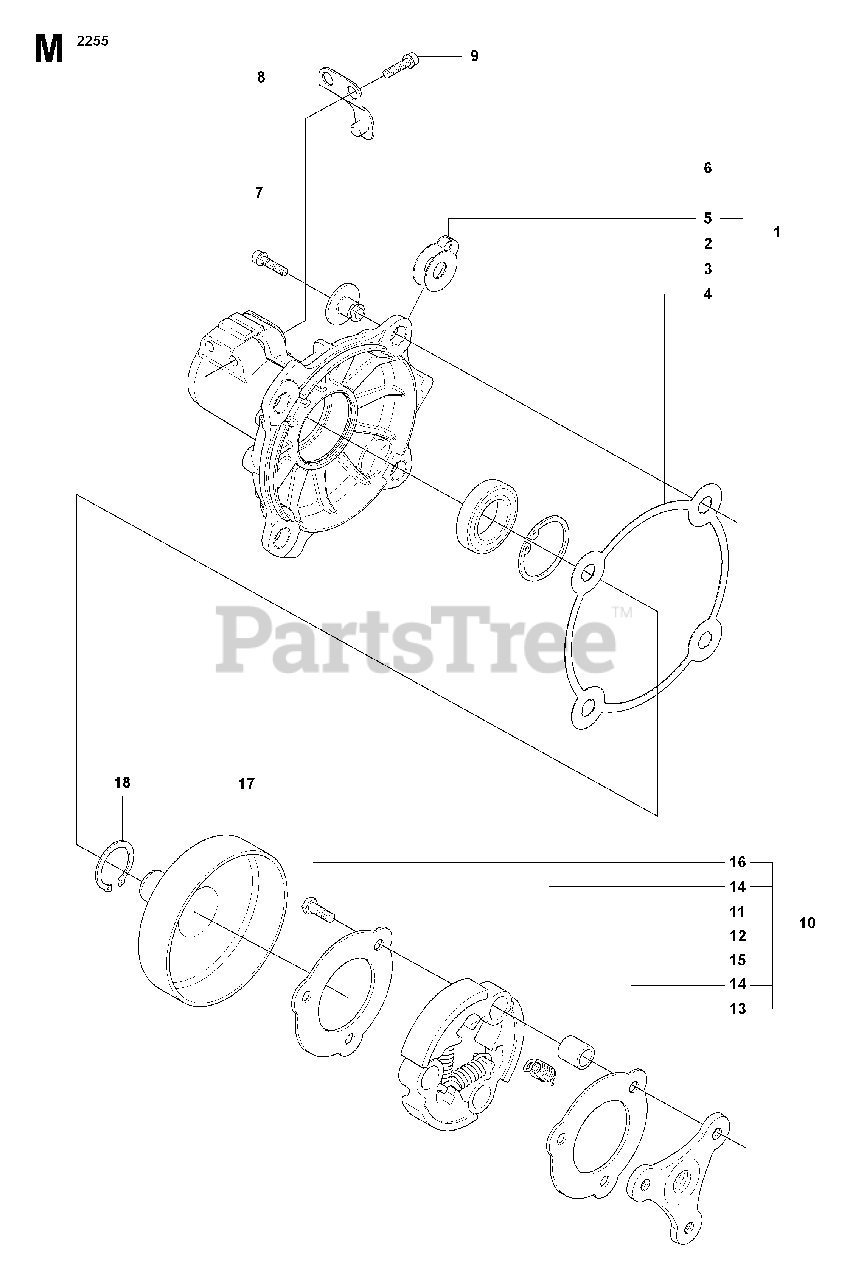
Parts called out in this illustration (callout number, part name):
1	RP CLUTCH COVER ASSY
2	BALL BEARING 6202-2RS1
3	RETAINING RING SGH 35
5	SPRING PLATE
6	SPACING SLEEVE
8	LOCKING PLATE
10	RP CLUTCH ASSY
11	CLUTCH SHOE
12	CLUTCH SPRING
13	CLUTCH HUB
17	RP CLUTCH DRUM ASSY
18	RETAINING RING SGA 15
